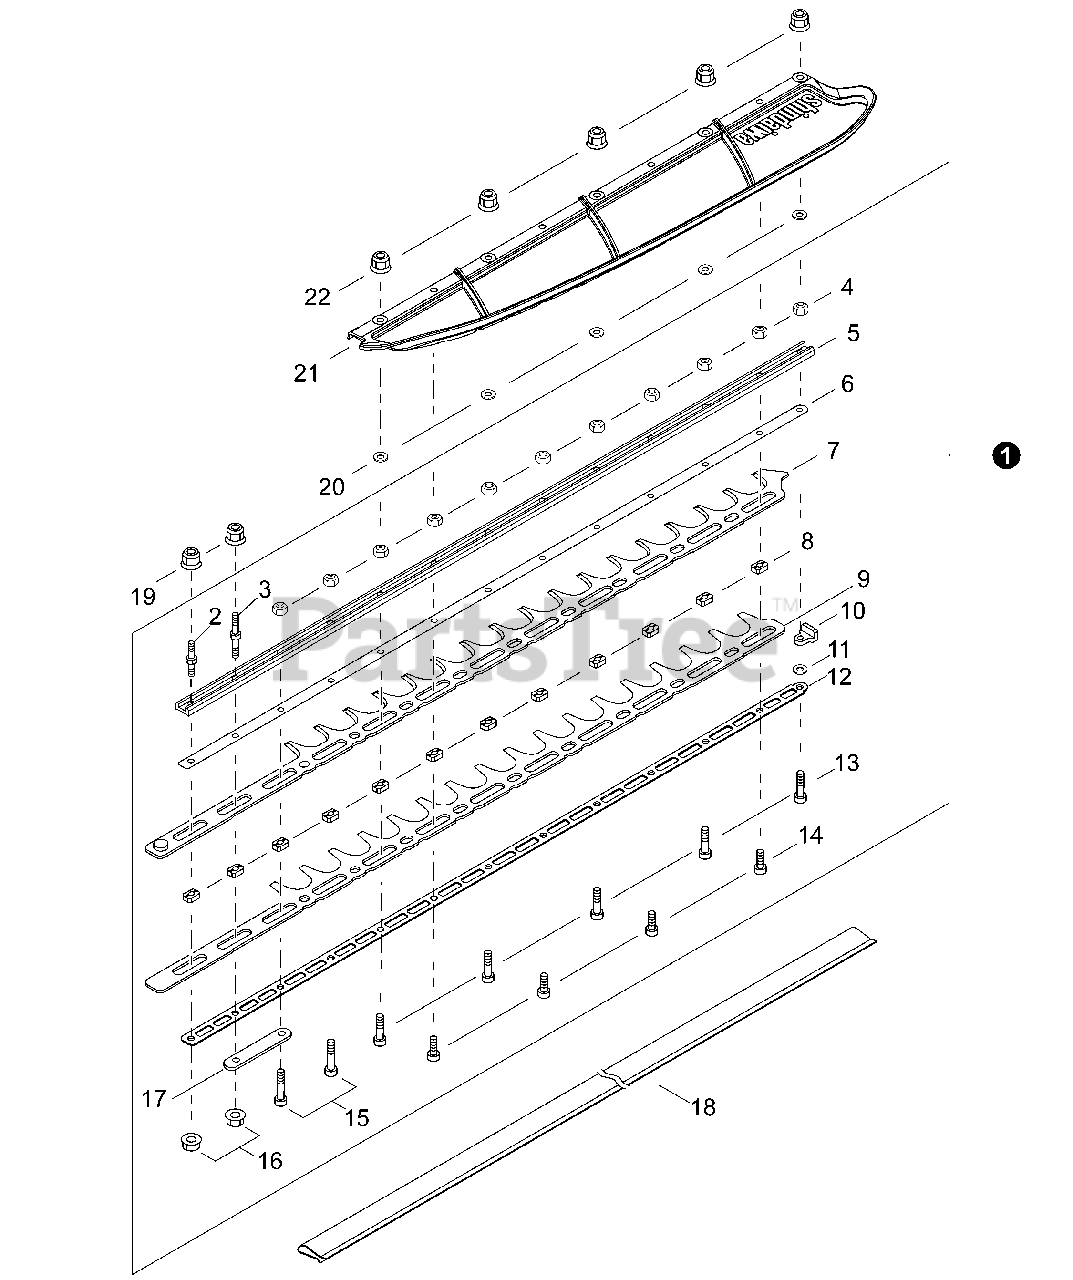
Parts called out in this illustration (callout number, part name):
1	CUTTER ASSY, 40"
2	STUD, MOUNTING M5
3	STUD, MOUNTING M5
5	SUPPORT, CUTTER 40"
6	SUPPORT, CUTTER 40"
7	CUTTER 40"
9	CUTTER 40"
12	SUPPORT, CUTTER 40"
13	BOLT, TORX 5×25
14	BOLT, TORX 5×16
15	BOLT, TORX 5×30
17	PLATE, EYE
18	SCABBARD
20	WASHER, FLAT 5.5×10×0.8
21	DEFLECTOR, DEBRIS
